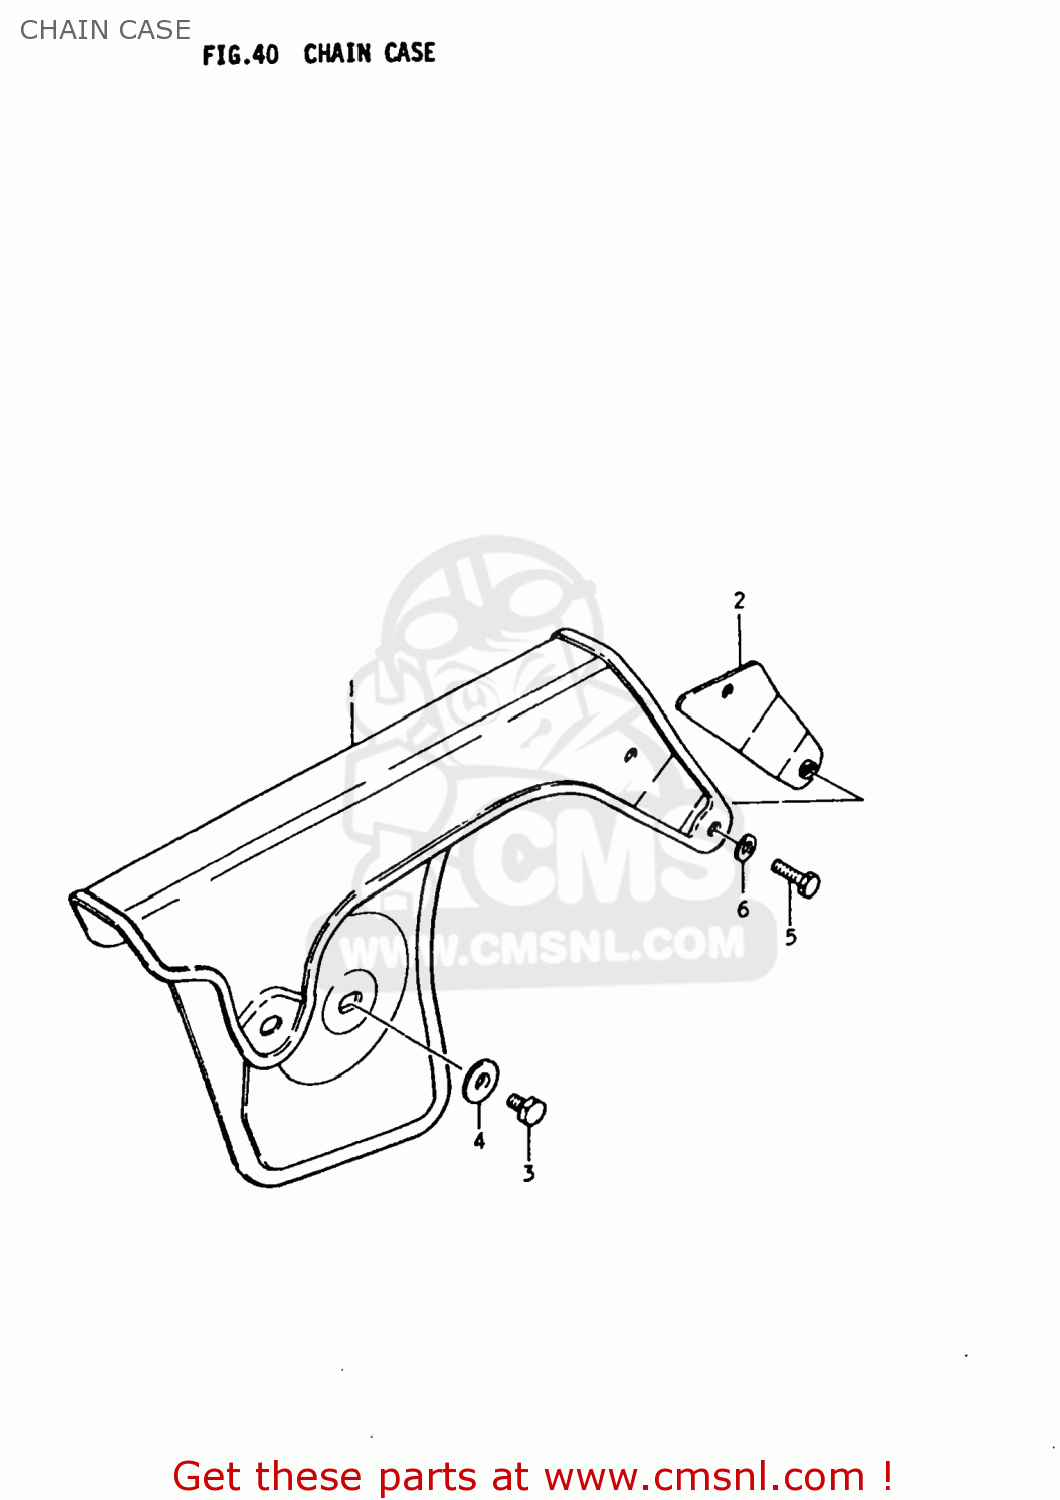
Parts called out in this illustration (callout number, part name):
1	CASE,CHAIN
2	REINFORCEMENT,CHAIN CASE
3	BOLT(6X8)
4	WASHER
5	BOLT
6	WASHER
